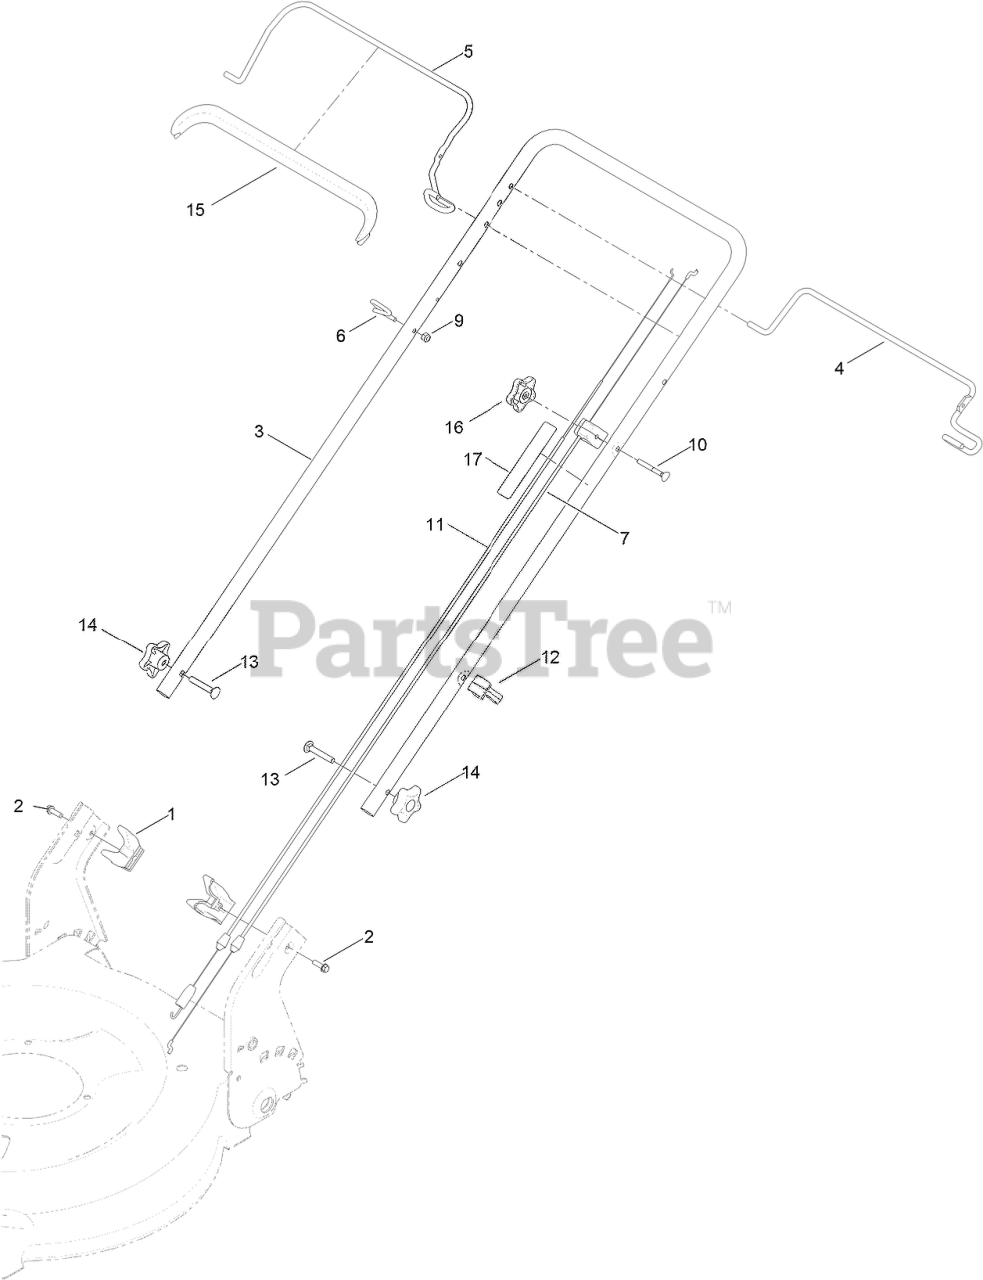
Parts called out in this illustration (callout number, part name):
1	ANCHOR-BAG
2	SCREW-HWH
4	BAIL-TRACTION
5	BAIL-BRAKE
6	GUIDE-ROPE
7	CABLE-BRAKE
9	NUT-LOCK, NI
10	SCREW-HANDLE
11	CABLE-TRACTION
12	GUIDE-CABLE
13	Screw-CARR
14	KNOB-HANDLE
15	COVER-BAIL
16	KNOB-HANDLE, LOCKING
17	DECAL-TRACTION, ADJUST
